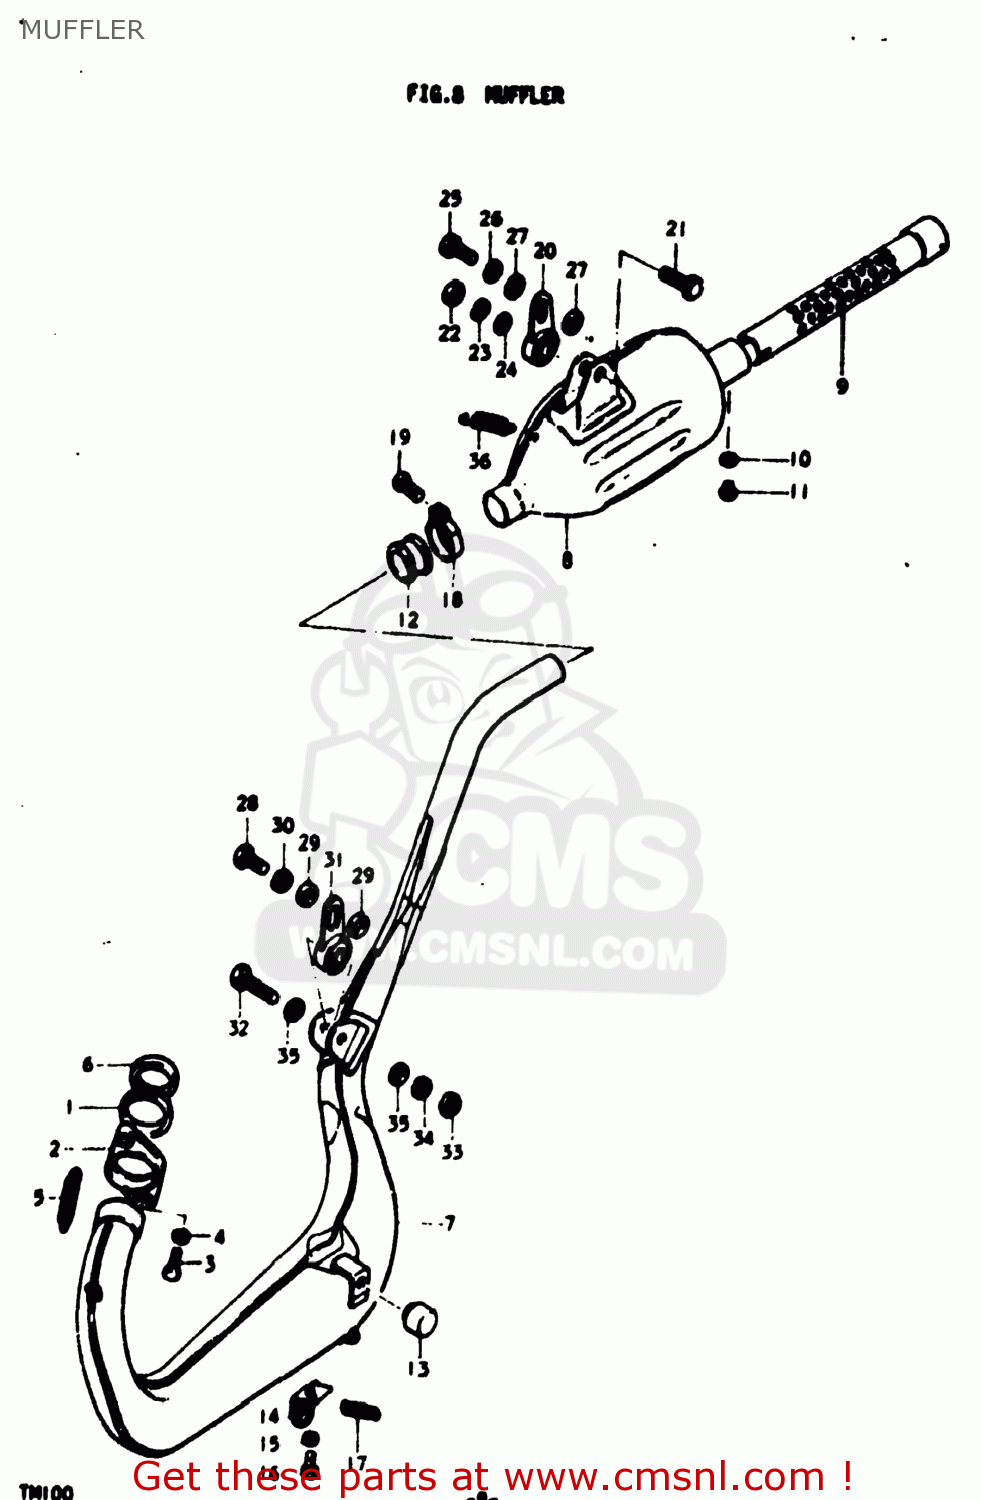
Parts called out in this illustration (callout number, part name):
1	GASKET,EXHAUST PIPE (NAS)
2	CLAMP,EXHAUST PIPE
3	BOLT
4	LOCK WASHER
5	SPRING
6	CUSHION,EXHAUST PIPE
7	BODY,MUFFLER
8	MUFFLER ASSEMBLY
9	PIPE,MUFFLER BAFFLE
10	LOCK WASHER
11	SCREW(6X8)
12	CONNECTOR,MUFFLER
13	CUSHION(11.5X22X20)
14	BRACKET, MUFFLER STOPPER
15	LOCK WASHER
16	BOLT
17	SPRING
18	CLAMP
19	CROSS HEAD SCREW
20	DAMPER,MUFFLER SUPPORT
21	BOLT
22	NUT
23	LOCK WASHER
24	WASHER
25	BOLT
26	LOCK WASHER
27	WASHER
28	BOLT
29	WASHER
30	LOCK WASHER
31	DAMPER,MUFFLER SUPPORT
32	** SUPERSEEDED
33	NUT
34	LOCK WASHER
35	WASHER
36	SPRING
